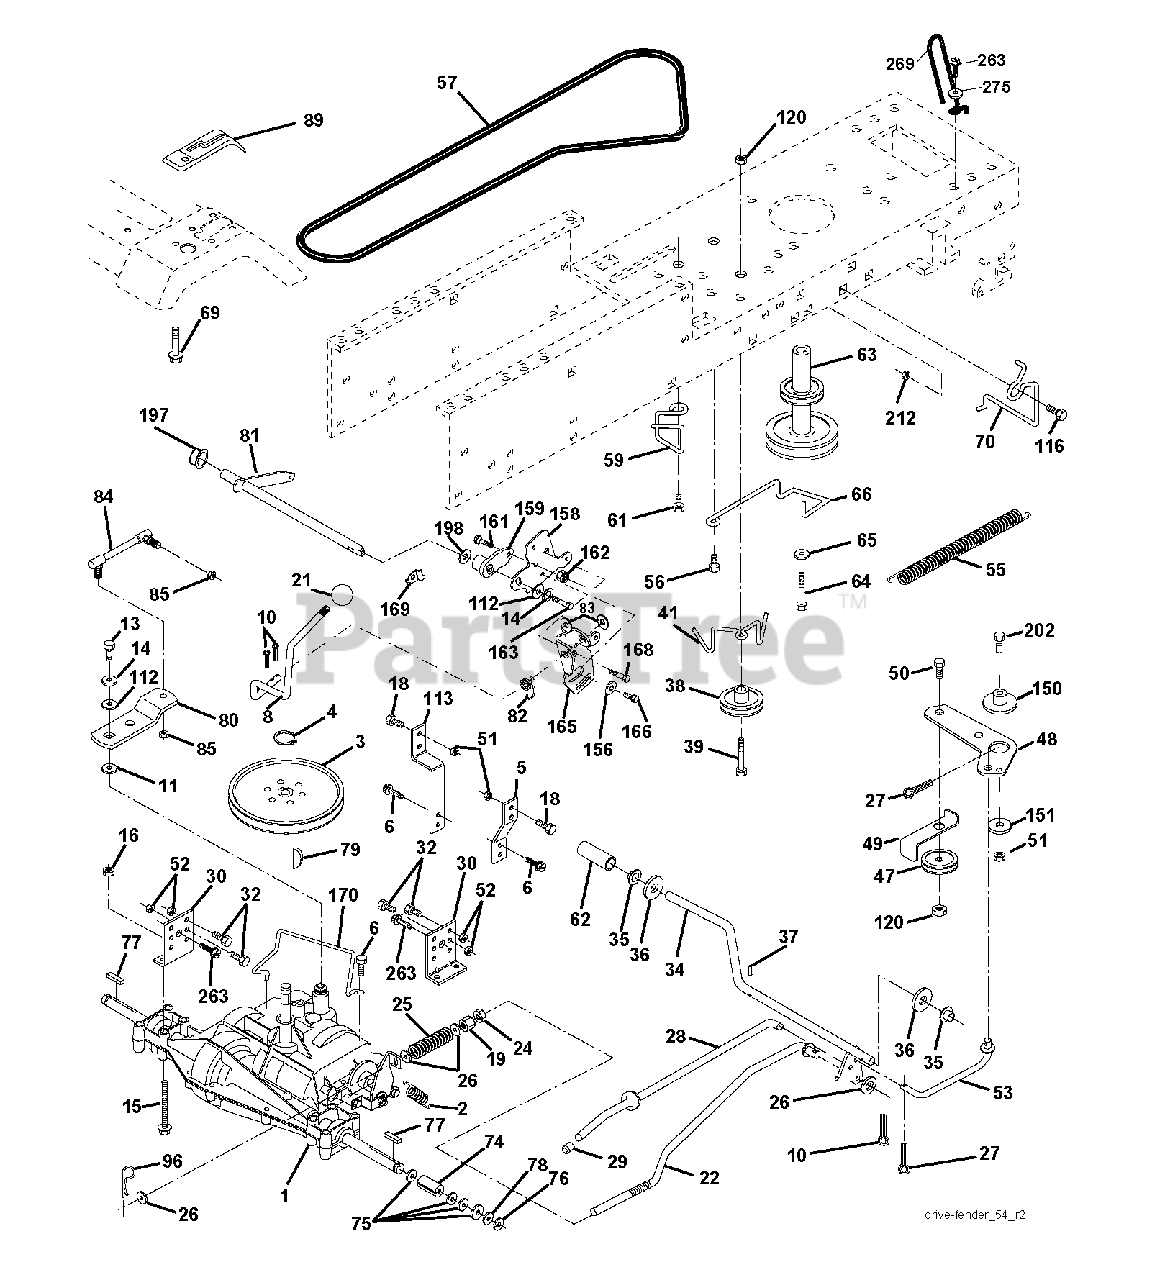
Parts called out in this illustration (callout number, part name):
2	SPRING,BRAKE RETURN
3	PULLEY TRANS
4	RETAINING RING LT
5	STRAP TORQUE
6	SCREW 5/16"
8	ROD SHIFT FENDER ADJUST LT
10	PIN COTTER
11	WASH-SHFT PLT LT
13	BOLT 1/4-28X3/4
14	LOCKWASHER
15	BOLT HEX 5/16-18 GR 5
16	NUT.71038.31-18.HEX.NYLOCK
19	NUT
21	KNOB T (1/2-HOLE)
22	ROD BRAKE
24	NUT
25	SPRING ROD LT
27	COTTER PIN
28	ROD, PARKING BRAKE
29	PLUNGER CAP
30	BRKT, MOUNT TRNSAXLE
32	BOLT
34	SHAFT, FOOT PEDAL
35	BEARING.NYLON
36	WASHER LT
37	DRIVE PIN
38	PULLEY IDLER COMPOSITE
41	KEEPER, BELT IDLER
47	IDLER PULLEY
48	BELLCRANK, CLUTCH
49	RETAIN BELT
50	BOLT.3/8-16X1.50
51	LOCKNUT
52	LOCKNUT
53	LINK.CLUTCH.7.66.2005
55	SPRING, RETURN LT
56	SCREW.3/8-16
57	BELT, V GROUND DRIVE 95 25
59	KEEPER, BELT CENTER
61	SCREW 3/8-16X.875
62	PEDAL COVER T
63	ENGINE PULLEY
64	BOLT HEX 7/16-20X4-1/4"
65	LOCKWASHER
66	KEEPER BELT ENGINE
69	SCREW.HI-LO.CONSOLE
70	KEEPER BELT ENG
74	SPACER AXLE
76	E-RING LT
77	SQUARE KEY
80	ARM SHIFT
82	SHIFT SPRING
83	WASHER
85	NUT LOCK CENTER 1/4 -28 FNTHD
96	RETAINER M
112	WASHER LT
113	STRAP TORQUE LH LT
116	BOLT D
120	NUT LOCK FLG 3/8-16 UNC
150	SPACER, RETAINER
151	WASHER 12/32X2X10GA
156	WASHER.SRRTD.5/16
158	BRACKET
159	HUB.SHIFT
161	BOLT
162	NUT.CROWNLOCK.1/4
165	RP BRACKET
168	BOLT.SHOULDER.5/16-18X
169	PLATE.FASTENING.CROSS.SHAFT
170	KEEPER BELT T/A
197	NYLINER SNAP 5/8" ID
198	WASHER.NYL.7/8IDX.105"HYD CR
202	BOLT
212	NUT
263	SCREW, 3/8-16X3/4
275	WASHER
